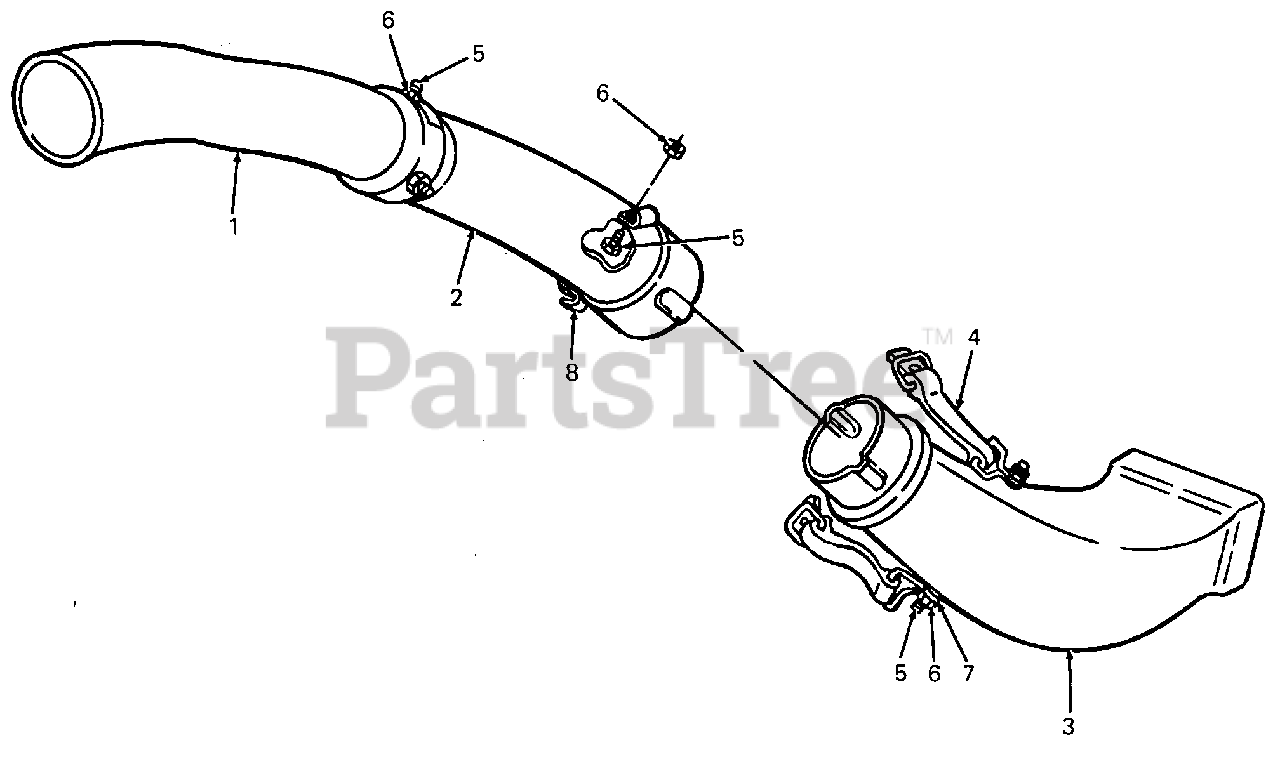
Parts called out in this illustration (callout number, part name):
1	Elbow, Catcher
2	Tube, Catcher
3	Discharge Chute
4	Strap Assy, Retainer
5	Screw, Hex, 1/4-20 X .50 Lg
6	Nut, Hex Insert Lock, 1/4-20
7	Washer, Spring, .265 ID X .562 OD
8	Hook Bracket, Retainer
